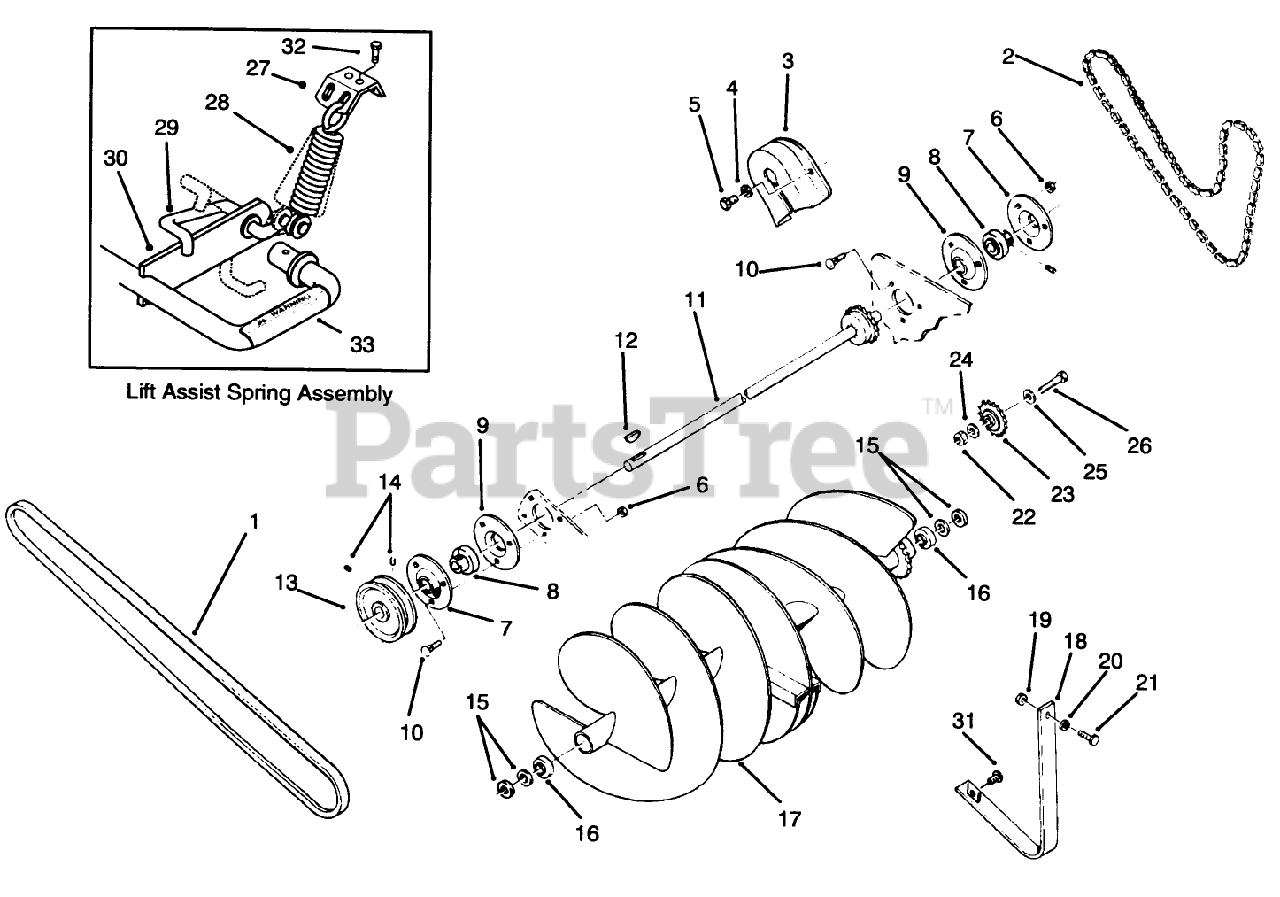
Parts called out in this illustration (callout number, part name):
1	Belt
2	CHAIN-64 PITCHES
3	GUARD-CHAIN
4	WASHER-FLAT
5	Bolt
6	NUT-LOCK, NI
7	FLANGE-ZERK RELUBE
8	BEARING AND COLLAR
9	Flange
10	BOLT-CARR
11	SHAFT W/SPRKT
12	Key
13	PULLEY
14	SCREW-SQH
15	WASHER-FLAT
16	BEARING-BALL
17	Auger Assembly
18	GUARD-INNER
19	NUT-KEPS
20	WASHER-FLAT
21	SCREW-HH
22	NUT-LOCK, NI
23	Sprocket-Idler
24	WASHER-FLAT
25	SPACER
26	SCREW-HH
27	BRACKET
28	SPRING-EXTENSION
29	SPRING ROD
30	SHAFT-GAGE
31	SCREW
32	SCREW-HH
33	DECAL-WARNING
